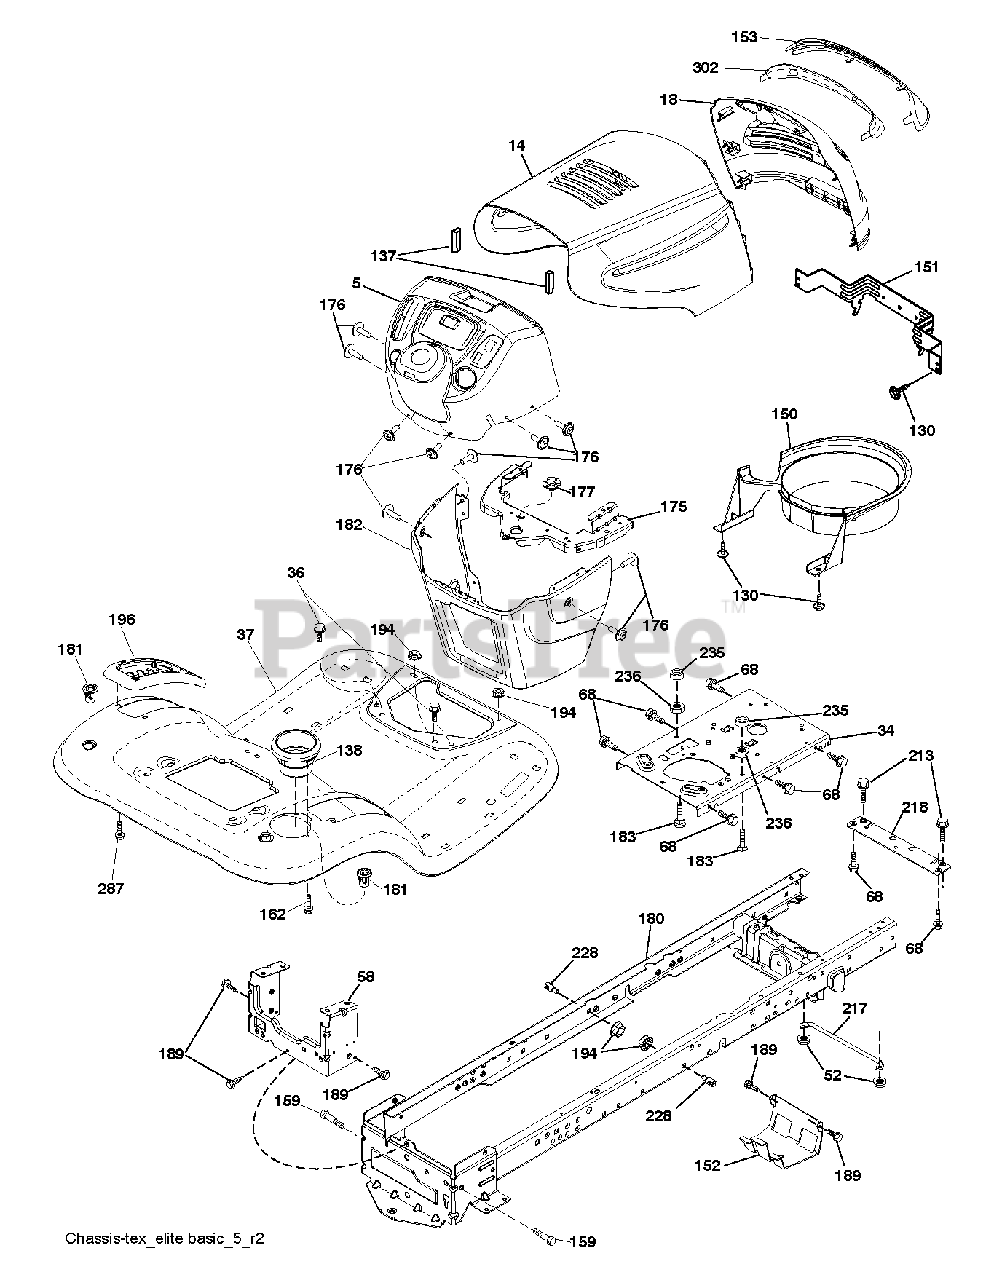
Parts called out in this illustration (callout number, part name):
5	DASH.P/L.TEX.CBL.CL.N/CHK.BLAC
14	HOOD.STL.ELITE.TOPLVRS.428
18	GRILLE.ELITE.BASIC.LT.BLACK
34	PLATE.ENGINE.WELDED.CHASSIS
36	SCREW 5/16"
37	FENDER.TLT.FS.W/CPH.428
52	LOCKNUT
58	DRAWBAR UPPER 2PC SMALL FENDER
68	SCREW LT
130	SCREW.#10 X 0.750.BOS (2 2)
137	BUMPER.HOOD.LARGE.1.75"
138	CUPHOLDER.TL.TEX.BLACK
150	DUCT.INTAKE.AIR.KAW
151	BRACKET PIVOT
152	SHIELD.BROWNING.W/TEX
153	LENS.GRILLE.BASIC.BAR.LT.CLR
159	SCREW, 3/8-16X3/4
162	SCREW.HI-LO.CONSOLE
175	CROSSMEMBER.LT
176	SCREW.#10-24X5/8.RN.QU
177	BUSHING STEERING
180	CHASS.WLDMNT.TL.12GA/2P.48/54
181	FEND/FTRST.PCH.CPH.NFW
182	DASH.LOWER.LT.CCS
183	BOLT.5/16-18X1-1/4 FULL THD
189	SCREW
194	NUT LOCK HEX FLANGE 5/16-18
213	BOLT
217	ROD.PIVOT.HOOD
218	X-PIECE.HOOD.STOP.NON/
228	STUD.FASTNER.W/ANTI-ROTATE
235	SPACER FENDER
236	NUT.CENTERLOCK.5/16-
287	SCREW 1/4X20
302	INSERT.LENS.REFLECTIVE.LEFT
